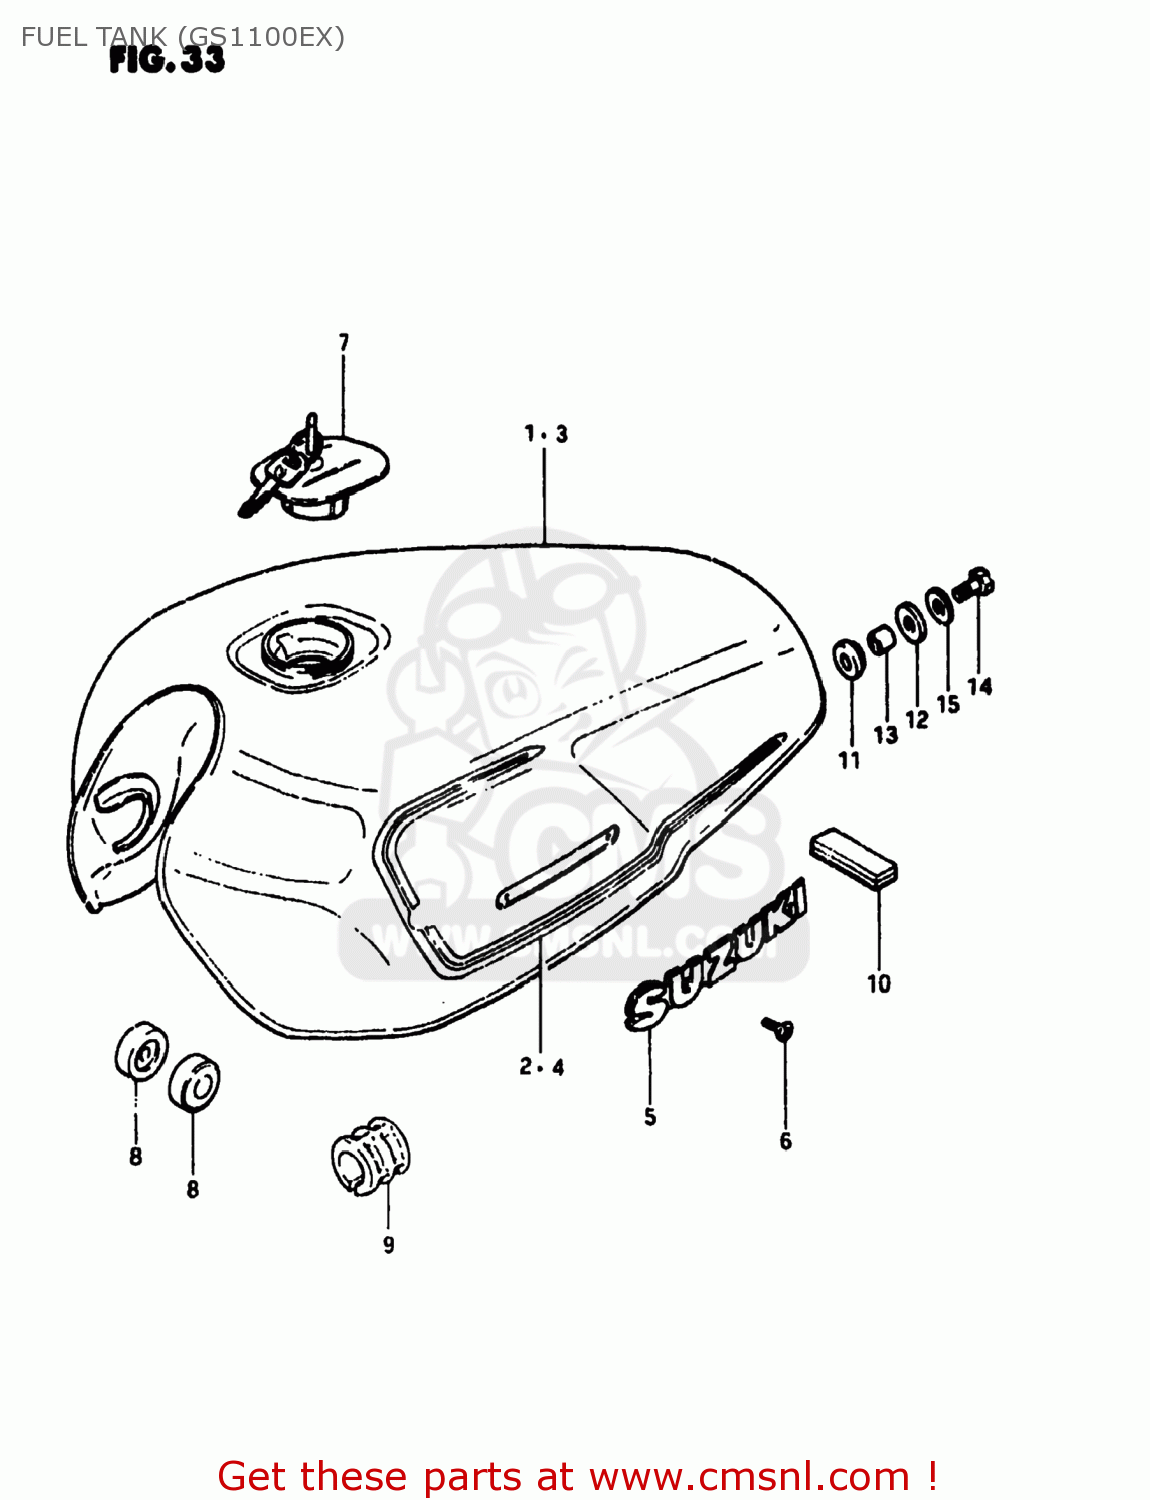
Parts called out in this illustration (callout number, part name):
1	TANK ASSEMBLY,FUEL
3	TANK ASSEMBLY,FUEL
5	EMBLEM,FUEL TANK
6	SCREW 3X6
7	CAP SET,FUEL TANK
8	CUSHION
9	CUSHION,FUEL TANK,UPPER
10	CUSHION
11	CUSHION
12	CUSHION
13	SPACER(8.5X12X19)
14	BOLT (8X30)
15	WASHER (8.5X29X1.6)
